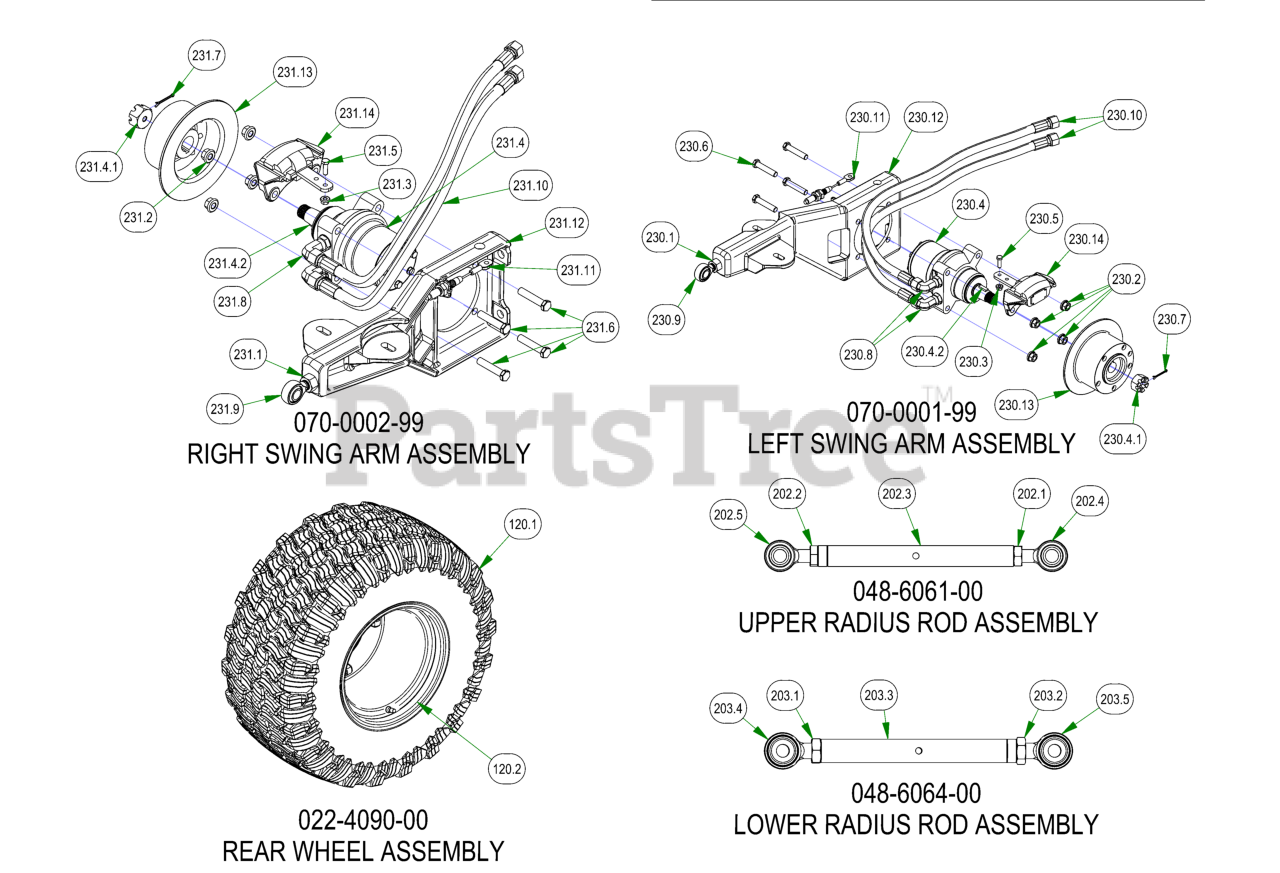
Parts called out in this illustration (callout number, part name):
120	2019 Assy-26x12-12 Reaper Turf -10.5" Rim
120.1	2019 26x12-12 Reaper Turf Tire
120.2	2019 10.5" Wheel
202	2019 Suspension Radius Rod Assembly
202.1	5/8-11 HEX JAM NUT ZINC
202.2	NUT, 5/8-18LH
202.3	2019 Suspension Link Body
202.4	2019 RH 5/8" Heim
202.5	2019 LH 5/8" Heim
203	2019 Suspension Radius Rod Assembly
203.1	3/4-16 HEX JAM NUT ZINC
203.2	3/4-16 LH HEX JAM NUT ZINC
203.3	Rear Radius Rod, 3/4 Body
203.4	3/4-16 x 5/8 RH Heim
203.5	3/4-16 x 5/8 LH Heim
230	2019 Renegade Trailing LH Arm Assy
230.1	3/4"-16 Fine Full Nut
230.2	1/2-13 Gr 8 Centerlock Flange Nut
230.3	5/16-18 NYLON INSERT FLANGE LOCKNUT ZINC
230.4	18cc Parker Wheel Motor- Left
230.4.1	1" Castle Nut for HydroGear Wheel Motor
230.4.2	Woodruff Key
230.5	5/16-18 X 1 HEX CAP SCREW (GR.5) ZINC
230.6	1/2-13 x 2.75 Gr. 8 Hex Head Bolt
230.7	1/8 X 1-1/2 COTTER PIN ZINC
230.8	2019 Rouge/Renegade Wheel Motor 90* Fitting #6801-10L
230.9	3/4-16 RH Male Rod End
230.10	2019 Renegade Hydro Hose
230.11	2019 Short Brake Cable-Suspension Models
230.12	2019 Left Trailing Arm
230.13	Brake Disk
230.14	XP/AOS Left Brake Caliper
231	2019 Renegade Trailing RH Arm Assy
231.1	3/4"-16 Fine Full Nut
231.2	1/2-13 Gr 8 Centerlock Flange Nut
231.3	5/16-18 NYLON INSERT FLANGE LOCKNUT ZINC
231.4	18cc Parker Wheel Motor- Right
231.4.1	1" Castle Nut for HydroGear Wheel Motor
231.4.2	Woodruff Key
231.5	5/16-18 X 1 HEX CAP SCREW (GR.5) ZINC
231.6	1/2-13 x 2.75 Gr. 8 Hex Head Bolt
231.7	1/8 X 1-1/2 COTTER PIN ZINC
231.8	2019 Rouge/Renegade Wheel Motor 90* Fitting #6801-10L
231.9	3/4-16 RH Male Rod End
231.10	2019 Renegade Hydro Hose
231.11	2019 Long Brake Cable-Renegade, Rogue
231.12	2019 Right Trailing Arm
231.13	Brake Disk
231.14	XP/AOS Right Brake Caliper
